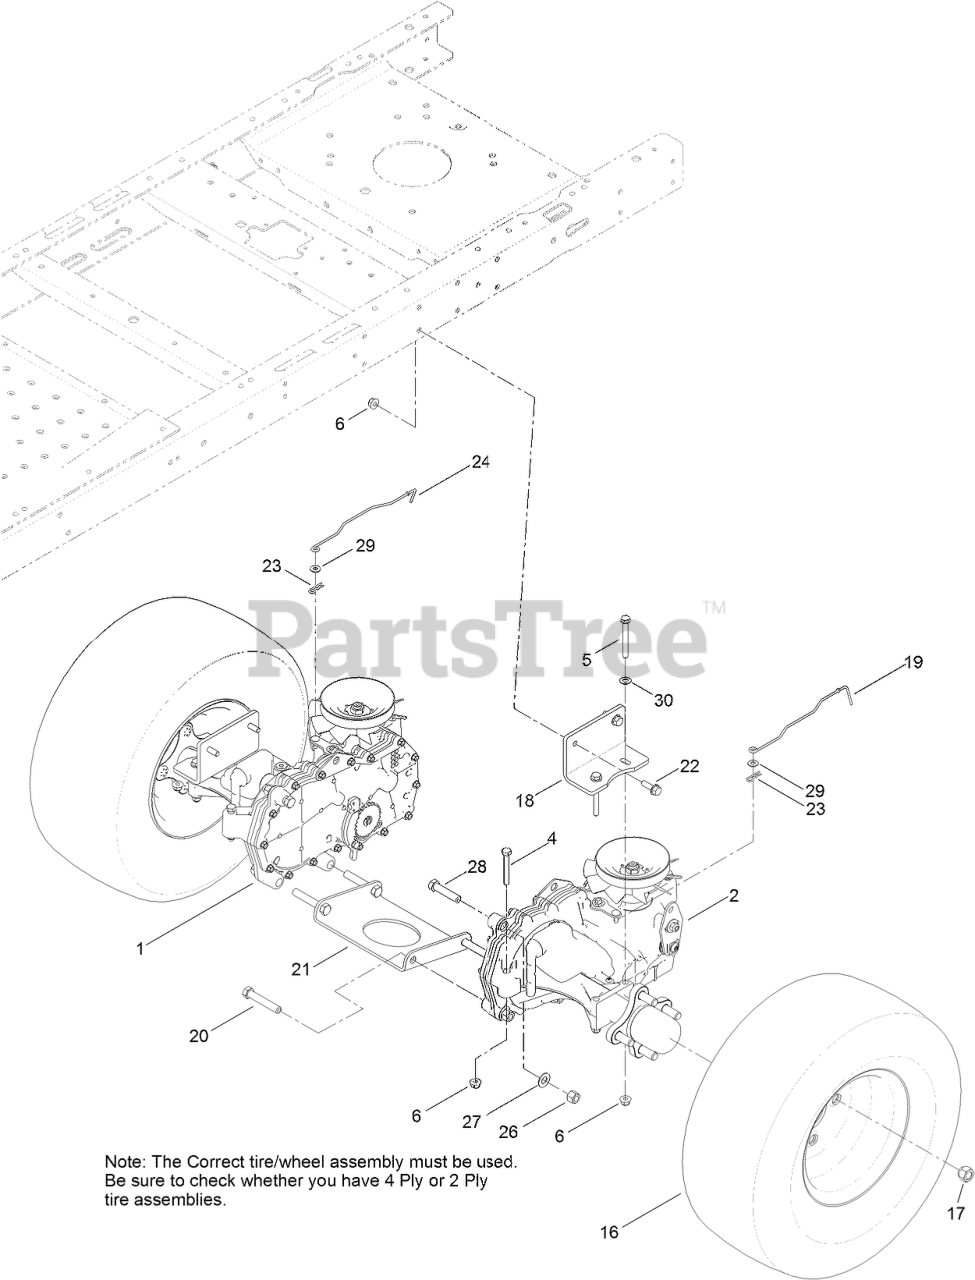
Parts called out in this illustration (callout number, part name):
1	RH HYDRO TRANSAXLE ASM
2	LH HYDRO TRANSAXLE ASM
4	SCREW-HH
5	SCREW-HH
6	NUT-HF, NI
16	4 PLY WHEEL AND TIRE ASM
16	2 PLY WHEEL AND TIRE ASM
17	NUT-LUG
18	MOUNT-HYDRO
19	ROD-BYPASS, LH
20	SCREW-HH
21	PLATE-CROSS, HYDRO
22	SCREW-HHF
23	PIN-COTTER
24	ROD-BYPASS, RH
26	NUT-LOCK, NI
27	WASHER-FLAT
28	SCREW-HH
29	WASHER
30	WASHER-PLAIN
